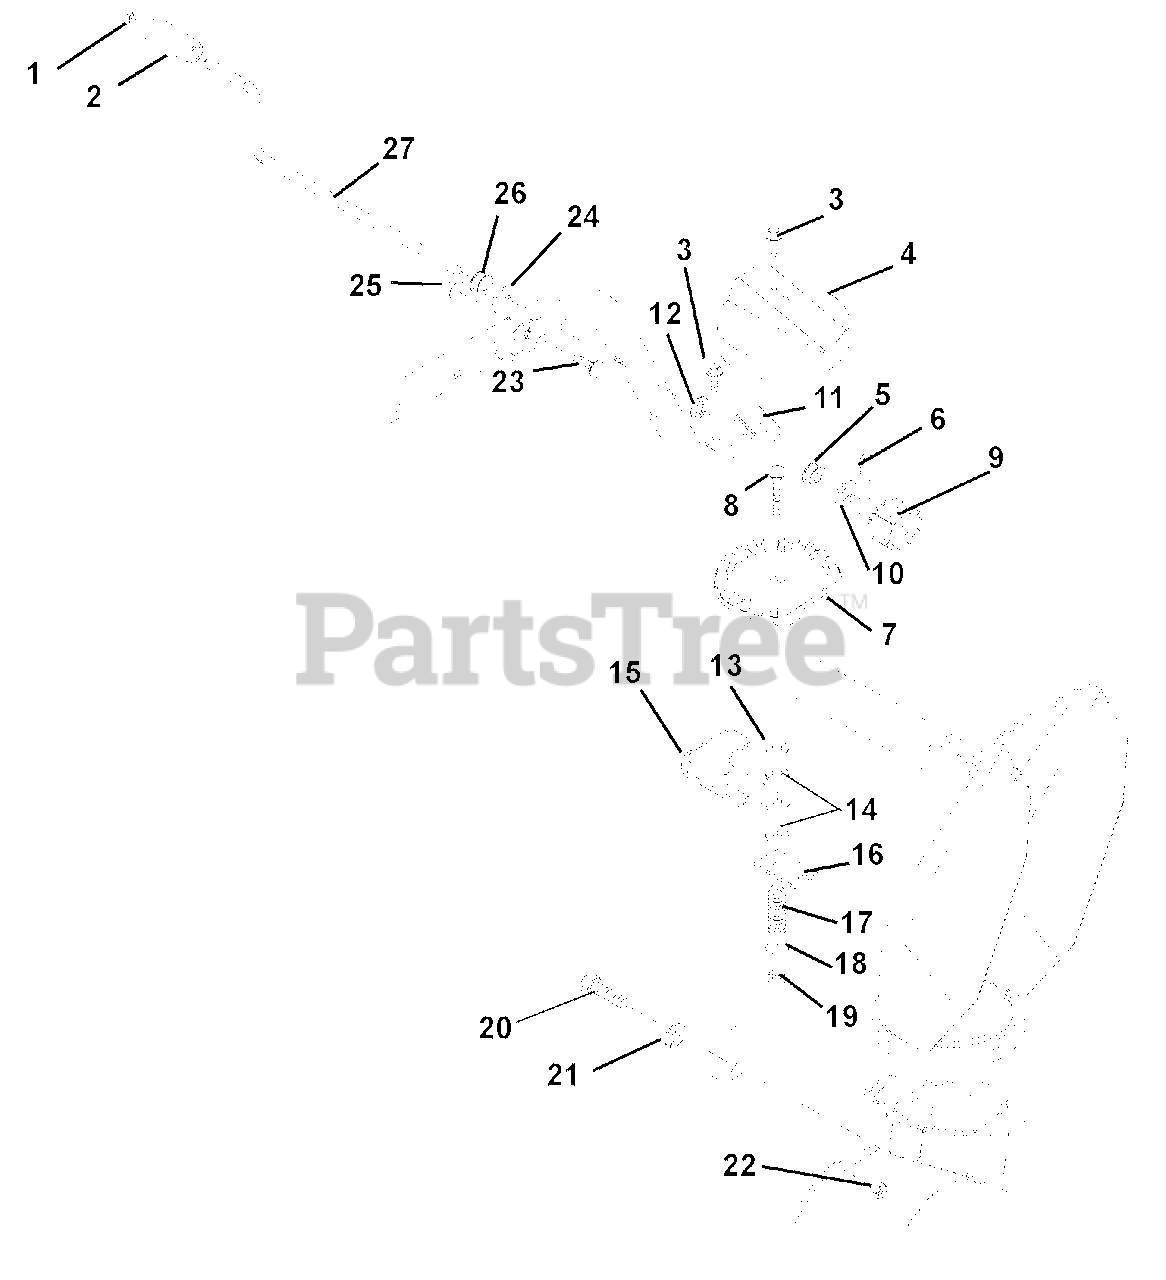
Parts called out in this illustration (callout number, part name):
1	CAP, 3/8 ROD YWZC
2	KNOB, CHUTE CRANK
3	@SCR-TAP .25-20X.50 HWH TR YWZ
4	GEAR COVER
5	BUSHING, POLYLINER-.63 SNAPIN
6	PIN, SPRING CLIP
7	CHUTE GEAR
8	@BLT-RDHDSQNK .38-16X2.50 G5YZ
9	BRACKET W/PINION GEAR
10	WSHR-THRST .625 X 1.0 X .03
11	BRACKET, PINION GEAR
12	PUSHNUT .625
13	WSHR-FL-STL .380X1.50X.062 YWZ
14	FRICTION WASHER
15	WELDMENT, PEDESTAL CHUTE MOUNT
16	PLATE, FRICTION
17	SG-COMP .187X.56X1.62
18	@WSHR-FL-STL.406X.812X.065 YWZ
19	@NUT-LK-CTR .38-16 YWZC
20	@BLT-HEX .38-16X1.75 GR5 YWZC
21	@WSHR-LK .38X.094 REG YWZC
22	@NUT-LK-TOP-FLG .38-16 YWZC
23	@BLT-RDHDSQNK .31-18X1.75 G5YZ
24	BRACKET, CRANK SUPPORT
25	@NUT-LK-TOP-FLG .31-18 YWZC
26	BUSHING, POLYLINER-.38 SNAPIN
27	ROD, CHUTE CRANK
